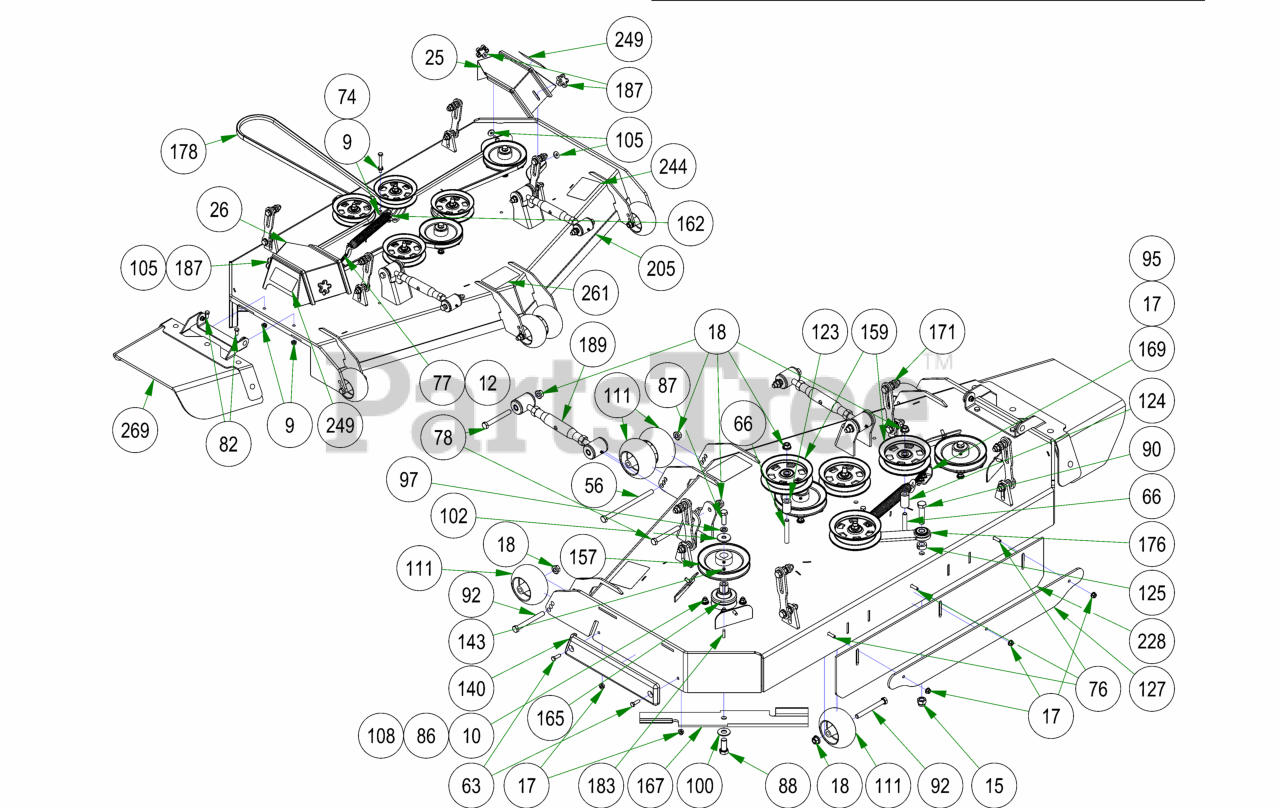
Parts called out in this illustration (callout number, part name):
9	3/8-16 HEX SERRATED FLANGE NUT HARD/ZINC
10	3/8-16 NYLON INSERT FLANGE LOCKNUT (GR.F) ZINC
12	3/8-16 HEX NUT ZINC
15	5/8-11 NYLON INSERT LOCKNUT ZINC
17	5/16-18 NYLON INSERT FLANGE LOCKNUT ZINC
18	1/2-13 NYLON INSERT FLANGE LOCKNUT ZINC
25	2019 61" Outlaw Gen2 Pulley Cover Left
26	2019 61" Outlaw Gen2 Pulley Cover Right
56	1/2-13 X 8 HEX CAP SCREW GR 5 ZINC
63	5/16-18 X 1 HEX CAP SCREW (GR.5) ZINC
66	1/2-13 X 3-1/2 HEX FLANGE BOLT (GR.8) ZINC
74	3/8-16 X 3 HEX CAP SCREW (GR.5) ZINC
76	5/16-18 X 1-1/4 CARRIAGE BOLT ZINC
77	4" 3/8-16 Eye Bolt
78	1/2-13 X 4 HEX CAP SCREW (GR.8) ZINC YELLOW
82	3/8-16 X 3/4 HEX CAP SCREW (GR.5) ZINC
86	3/8-16 X 1-1/2 HEX CAP SCREW (GR.5) ZINC
87	1/2-20 X 1-1/2 HEX CAP SCREW (GR.5) ZINC
88	5/8-18 X 1-1/2 HEX CAP SCREW (GR.8) ZINC YELLOW
90	5/8-11 X 2-1/2 HEX CAP SCREW (GR.5) ZINC
92	1/2-13 X 4-1/2 HEX CAP SCREW (GR.5) ZINC
95	5/16-18 X 7/8 CARRIAGE BOLT ZINC
97	1/2 SPLIT LOCKWASHER (GR.8) ZINC/YELLOW
100	5/8 USS FLAT WASHER (1-3/4" OD) GR.8 ZINC YELLOW
102	1/2 BELLEVILLE WASHER (1-5/8 OD X .140 THK) ZINC
105	.360 ID X .983 OD X .120 THICK FLAT WASHER NYLON BLACK
108	5/16 USS FLAT WASHER (7/8 OD) ZINC
111	2019 Deck Wheel
123	.502 ID X .750 OD X 1.500 Long Spacer
124	1 3/4" Pulley Spacer
125	5/8 SOLID SHAFT COLLAR (W/1 SET SCREW) ZINC
127	61 Bolt in Baffle Deck v2 Stripping Plate
140	REVISED TRIM BUMPER_20180226
143	5/16-24 X 1/4 SOCKET SET SCREW (CUP PT) PLAIN
157	6 1/4" Drive Pulley
159	5-3/4 Idler Pulley
162	2019 Outlaw Gen2 Deck Spring
165	OUTLAW SPINDLE ASSEMBLY
167	61 inch Fusion Blade
169	2019 Deck Eye Bolt Tab
171	Deck Hangar Assembly
176	2019 Rebel Rogue Deck Idler
183	1/4 X 1 SQ MACHINERY KEY 1018 STL PLN
187	5/16" Knob
189	Turnbuckle
205	2019 Sloped 61" Deck
228	R Series Rubber For Deck
244	2018 61" Deck Decal
249	Danger Decal-Spindle/Discharge
261	2019 Rebel & Rogue Deck Belt Route Decal
269	2019 Outlaw Gen2 Chute Assembly
